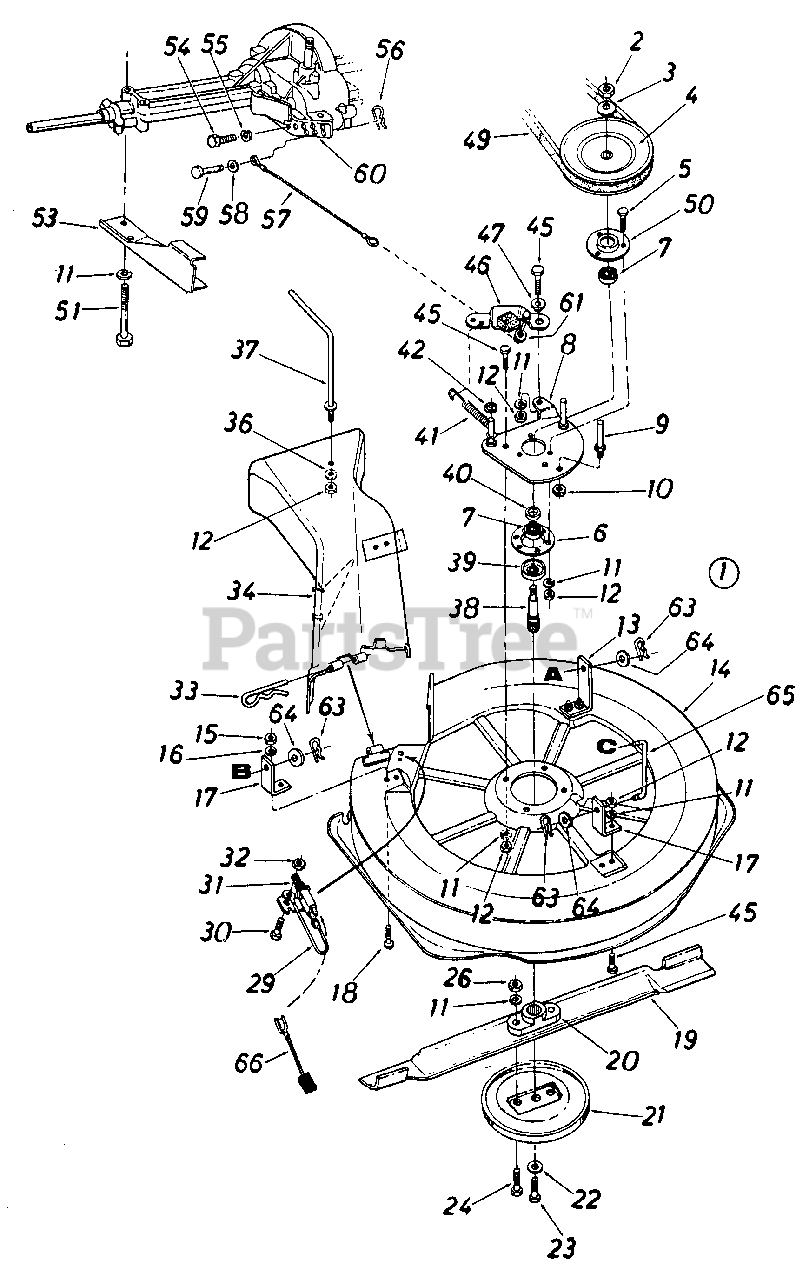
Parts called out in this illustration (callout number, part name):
1	DECK ASSY-30IN-COMP
2	NUT-HEX JAM 5/8-18
3	WASHER-BELL
5	SCREW-HEX SEMS 5/16-18 X .62
6	HOUSING-BRG
7	BEARING-BALL
8	PLATE-MTG-SPINDLE
9	STUD-3/8-16X2.75
10	NUT-HEX JAM 3/8-18
11	WASHER-LOCK-5/16
12	NUT-HEX CENTER L-5/16-18
13	BRACKET-HANGER
18	SCREW-TRUSS MACH 5/16-18 X .75
19	BLADE-30IN-RD
20	ADAPTER-BLADE
21	PLATE-ANTI SCALP
22	WASHER-LOCK-3/8
23	BOLT-3/8 NF X 1"GR5
24	SCREW-HEX SPECIAL 5/16-24X1.0
26	NUT-5/16-24
29	WIRE-REV LOCKOUT
30	SCREW-HEX 1/4-20 X .50
31	SWITCH-SAFETY
32	NUT-HEX 1/4-20
33	PIN-COTTER
34	DEFLECTOR-CHUTE RD
36	WASHER-SHAKE PROOF
38	SPINDLE-BLADE
39	SHIELD-BRG
41	SPRING-EXTENSION
45	SCREW-HEX 5/16-18 X .75
46	BRACKET ASSY
47	SPACER-SHLD
49	BELT-V 1/2 X 52
50	HOUSING-BRG
51	SCREW-HEX 5/16-18 X 2.75
53	GUARD-BELT-LOWER
54	SCREW-HEX 1/4-20 C .62
55	LOCK WASHER 1/4 DIA
56	PIN-INTERN COT-5/16 DIA
57	CABLE ASSY-BRAKE
58	WASHER-FL-.281 ID X .50 OD X .063
59	PIN-CLEVIS-1/4X1/2
60	GUARD-BELT-LOWER
63	PIN-INTERN COT
64	WASHER-FL-.531 X .930 OD X .050
65	LINK-DECK
